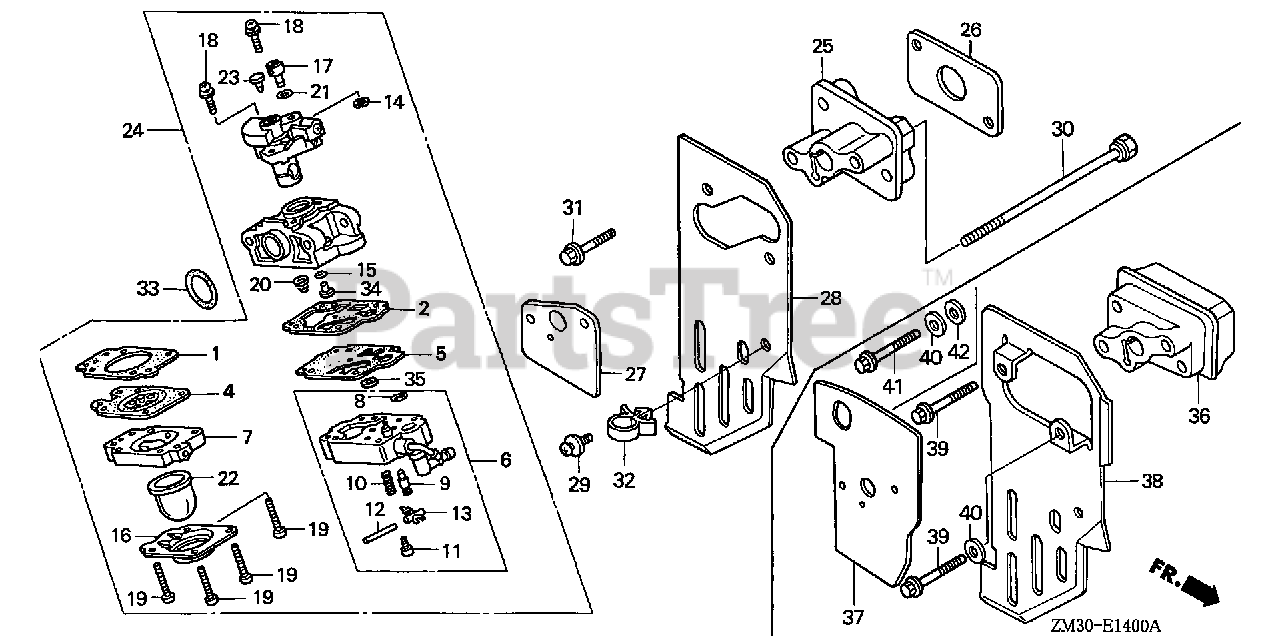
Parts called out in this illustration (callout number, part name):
1	GASKET, METERING DIAPHRAGM
2	GASKET, PUMP (CARBURETOR NO.)
4	DIAPHRAGM ASSY., METERING
5	DIAPHRAGM, PUMP
6	BODY ASSY., PUMP (CARBURETOR NO.)
7	BODY ASSY., AIR PURGE
8	SCREEN, INLET (CARBURETOR NO.)
9	VALVE, INLET NEEDLE
10	SPRING, METERING LEVER
11	SCREW, METERING LEVER PIN
12	PIN, METERING LEVER
13	LEVER, METERING
14	RING, SPRING RETAINING
16	COVER, PRIMER PUMP
18	SCREW, THROTTLE COLLAR
19	SCREW, PUMP COVER
20	SPRING, PUMP
22	PUMP, PRIMER
24	CARBURETOR ASSY. (WYL 96)
24	CARBURETOR ASSY. (WYL 126)
25	INSULATOR, CARBURETOR
26	GASKET, INSULATOR
27	GASKET, CARBURETOR
28	GUIDE, AIR INLET
29	SCREW-WASHER (5X10)
30	BOLT, HEX. (5X75)
31	BOLT, FLANGE (5X22)
32	CLIP, WIRE HARNESS
33	O-RING (14.8X2.4)
34	JET (#31.5) (CARBURETOR NO.)
34	JET (#32.5) (CARBURETOR NO.)
34	JET (#33.5) (CARBURETOR NO.)
34	JET (#34.5) (CARBURETOR NO.)
34	JET (#35.5) (CARBURETOR NO.)
34	JET (#36) (CARBURETOR NO.)
34	JET (#37) (CARBURETOR NO.)
34	JET (#38) (CARBURETOR NO.)
35	FILTER, FUEL INLET (CARBURETOR NO.)
36	INSULATOR, CARBURETOR
37	GASKET, CARBURETOR
38	GUIDE, AIR INLET
39	BOLT, FLANGE (5X32)
